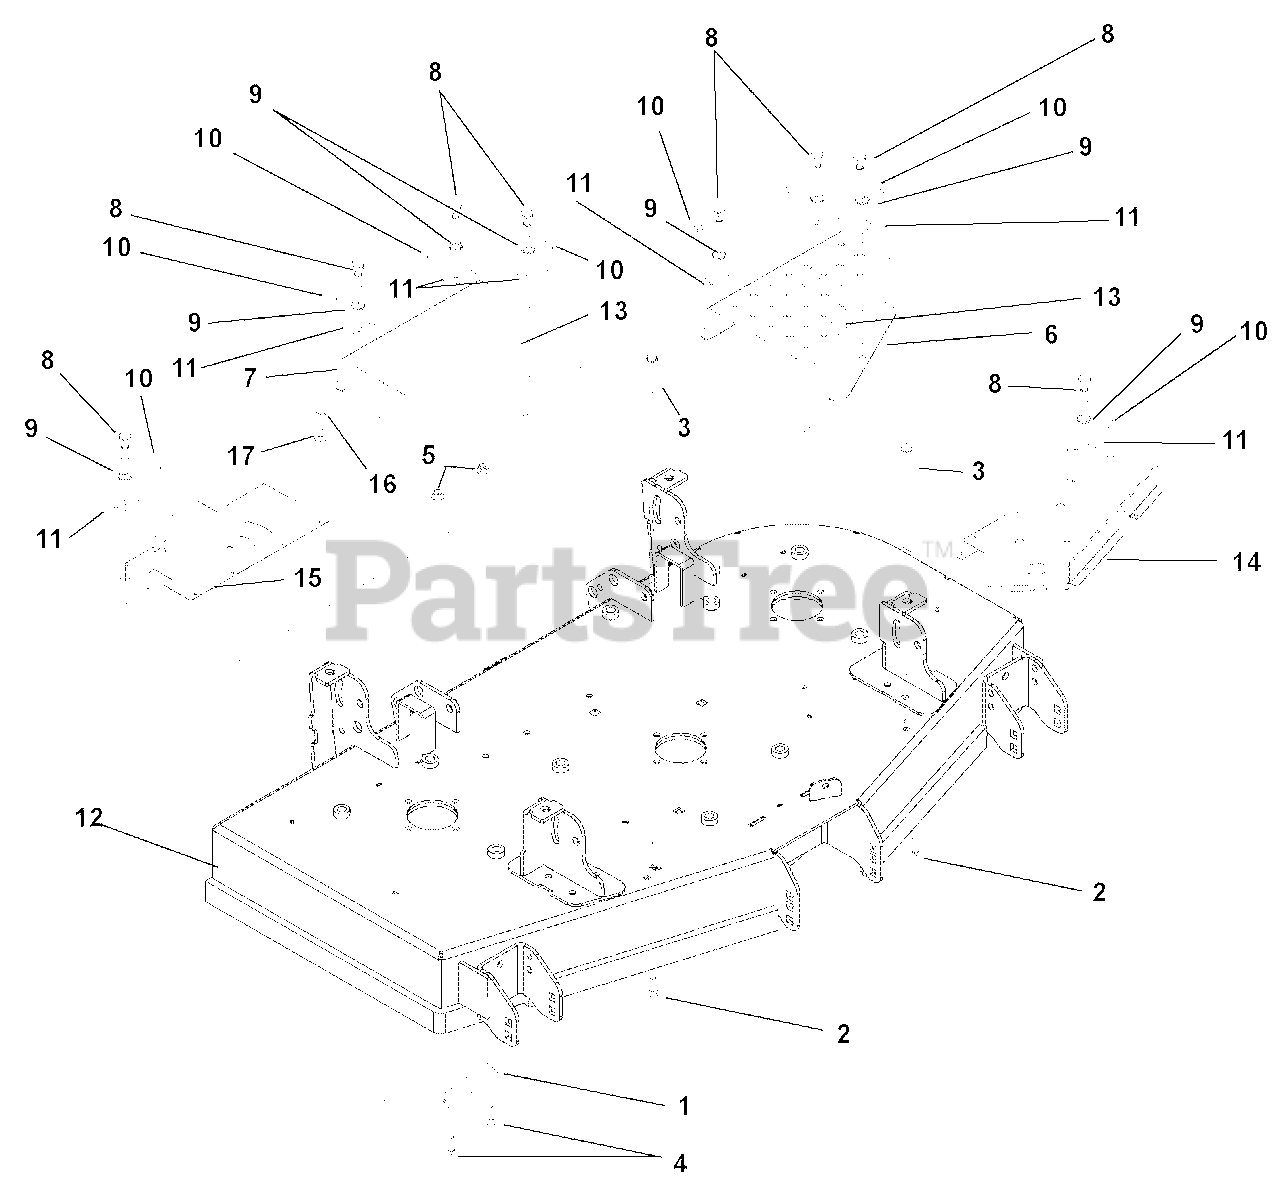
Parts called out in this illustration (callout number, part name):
1	Rear Discharge Deflect Baffle Weldment
2	Bolt, Round Head Square Neck .31 - 18 x .75
3	Nut, Coupling .31 - 18 x 3.00
4	Bolt, Round Head Square Neck .38 - 16 x 1.00
5	Nut, Locking-Nylon-Flange .38 - 16
6	Cover, Left Hand Belt, CE
7	Cover, Right Hand CE Belt
8	Bolt, Hex .38-16 x 1.25
9	Washer, Locking, EXT.391 x .682 x .036
10	Rivet, Pop .187
11	Keeper, Bolt
12	Weldment, 48" PT100 RR DISCH Deck
13	Decal, Pinch Point
14	Weldment, Front Belt Shield
15	Shield, Belt Rear
16	Bolt, Hex .25-20 x .75 Grade 5 YZ
17	Washer, Flat Steel .281 x .62 x .065 YZ
